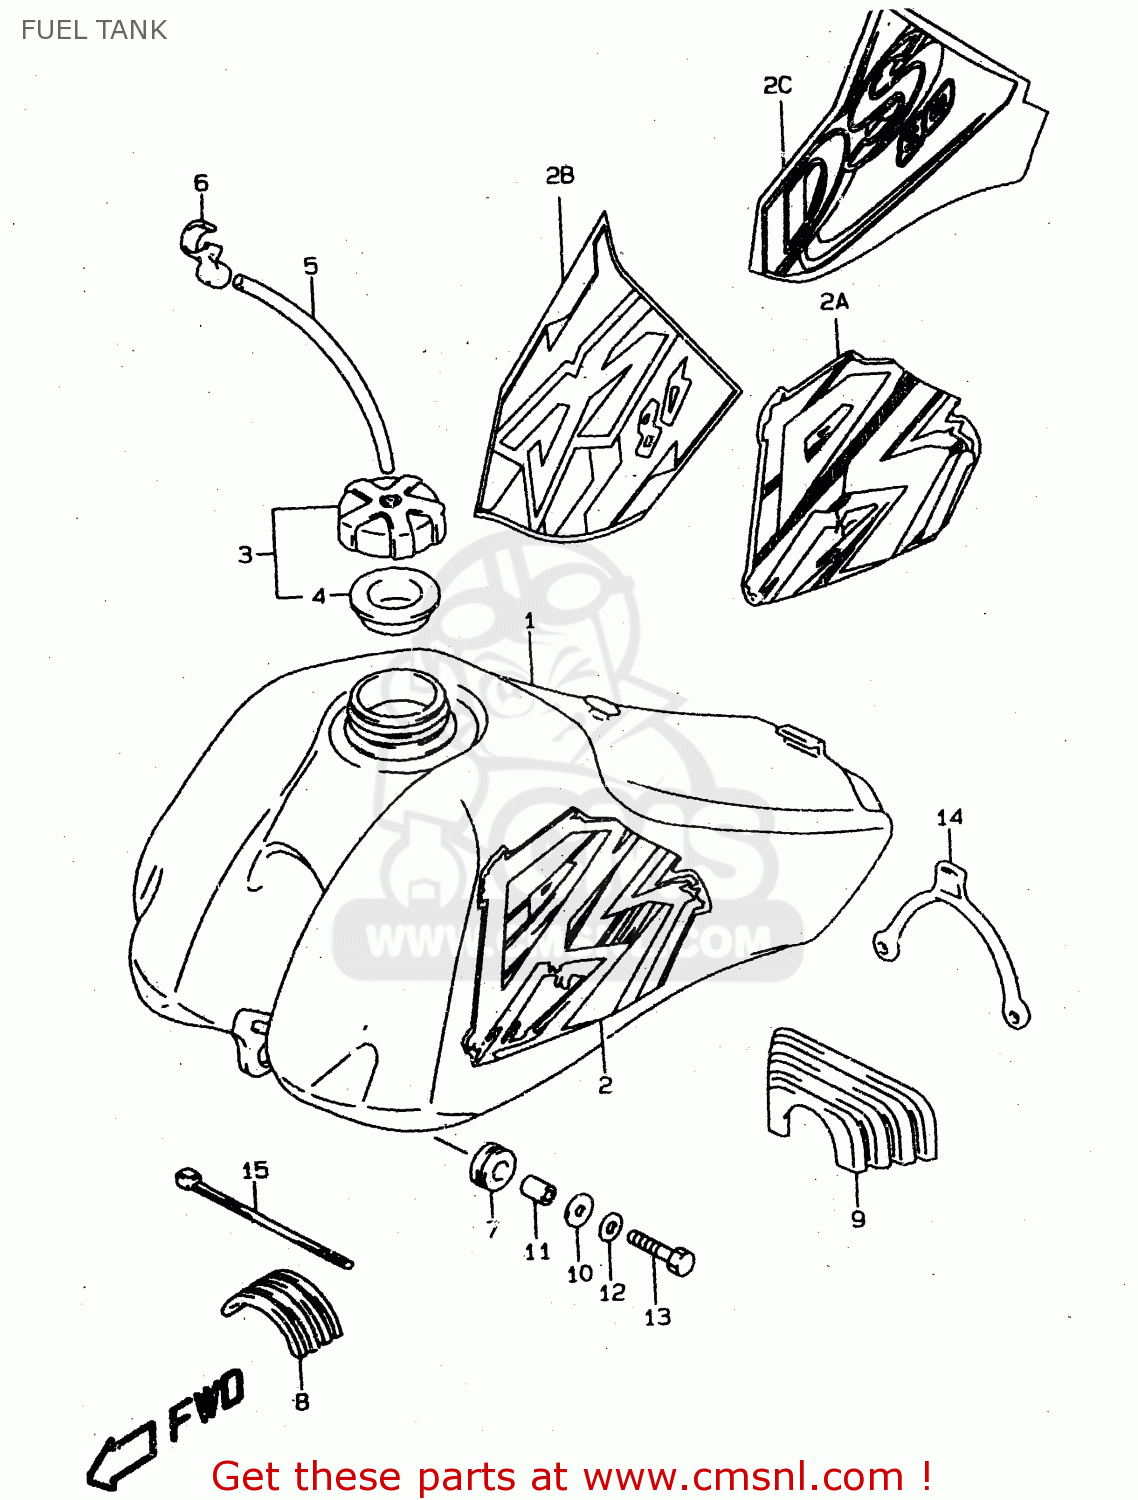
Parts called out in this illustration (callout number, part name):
1	TANK ASSY,FUEL(YELLOW)
2	EMBLEM SET,FUEL TANK
2A	EMBLEM SET,FUEL TANK
2B	EMBLEM SET,FUEL TANK
2C	EMBLEM SET,FUEL TANK
3	CAP SET,FUEL TANK
4	GASKET (NAS)
5	HOSE(5X8.2X600)
6	CLAMP
7	CUSHION
8	CUSHION,FUEL TANK UPR FR
9	CUSHION,FUEL TANK UPR RR
10	WASHER(6.5X24X1.6)
11	SPACER(6.5X10X13.5)
12	LOCK WASHER
13	BOLT
14	BAND,FUEL TANK RR
15	CLAMP
